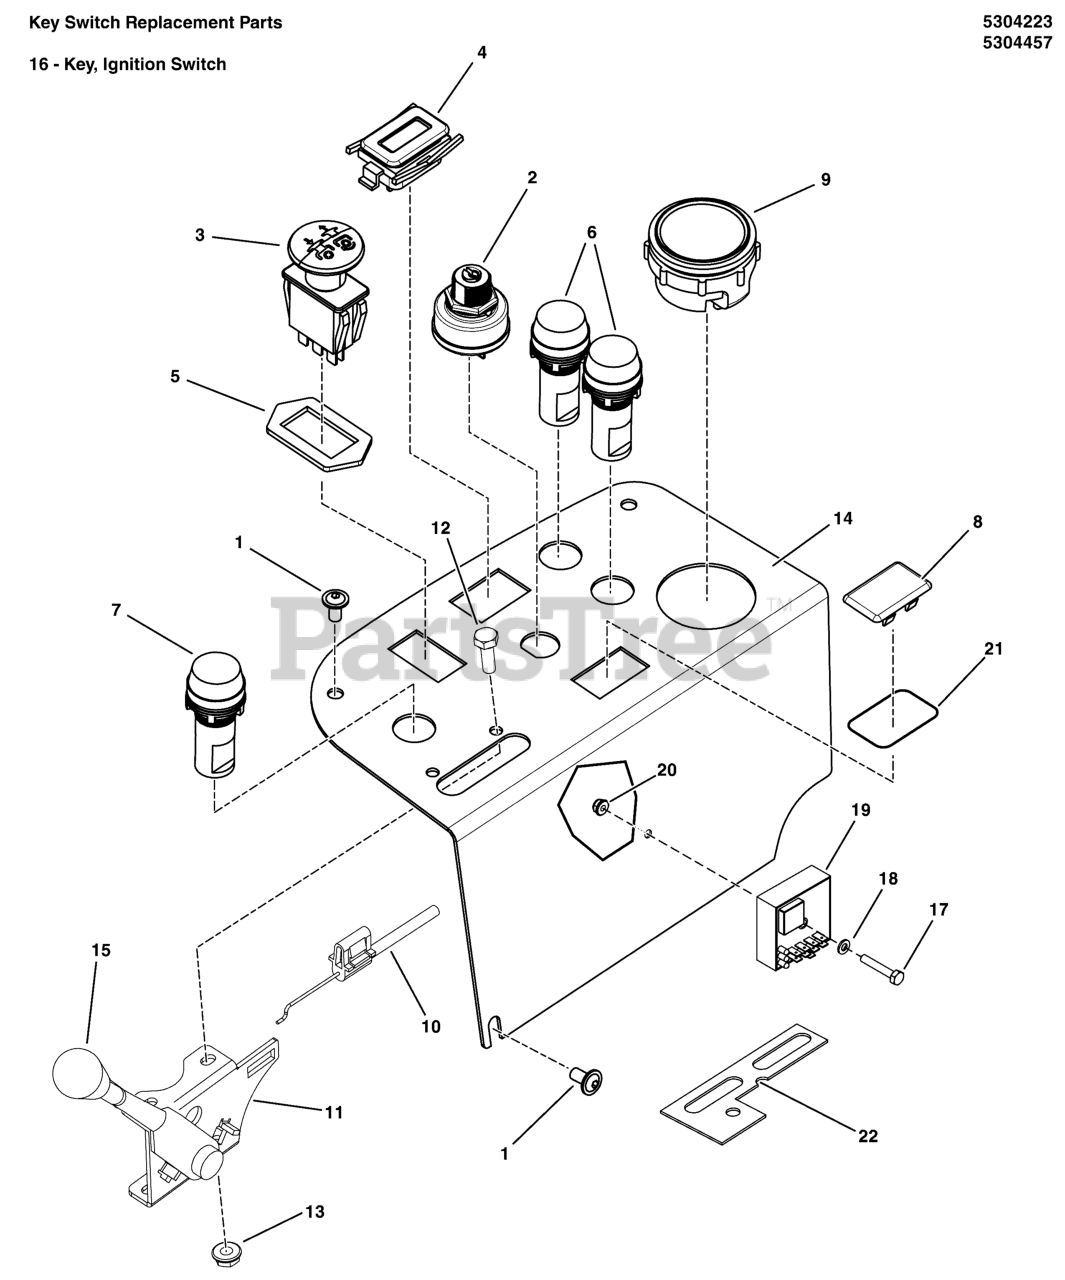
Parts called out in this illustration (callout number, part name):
1	SCREW, ALLEN HEAD 1/4-20X.500 ZINC PHOS
2	IGNITION SWITCH, SEALED, 3 POS
3	SWITCH-PTO PUSH
4	HOUR METER
5	RING, SWITCH RETAINER
6	LIGHT, WARNING, 22MM RED
7	LIGHT, GLOW PLUG, 22MM AMBER
8	PLUG, .820X1.44 HOLE, BLACK PLASTIC
9	GAUGE, WATER TEMPERATURE
10	CABLE, THROTTLE, 70"
11	LEVER, THROTTLE, HEAVY DUTY, IS2600
12	SCREW, #10-24 X 3/4" ROUND PHILLIPS
13	NUT, Hex, Nylon Lock, #10-24
14	PANEL, CONTROL, IS2600Z - BLK
15	THROTTLE CONTROL HANDLE/KNOB
16	KEY SET, Ignition Switch, 3 position (SV)
17	BOLT, 1/4-20 X 1-1/2 GD5 CZ
18	WASHER, 1/4 SAE
19	MODULE,DCK SHUT OFF W/DELY,175/2500/5100
20	NUT, 1/4-20 Hex Nylock Flange
21	O-RING, 7/8" ID X 1/16" W
